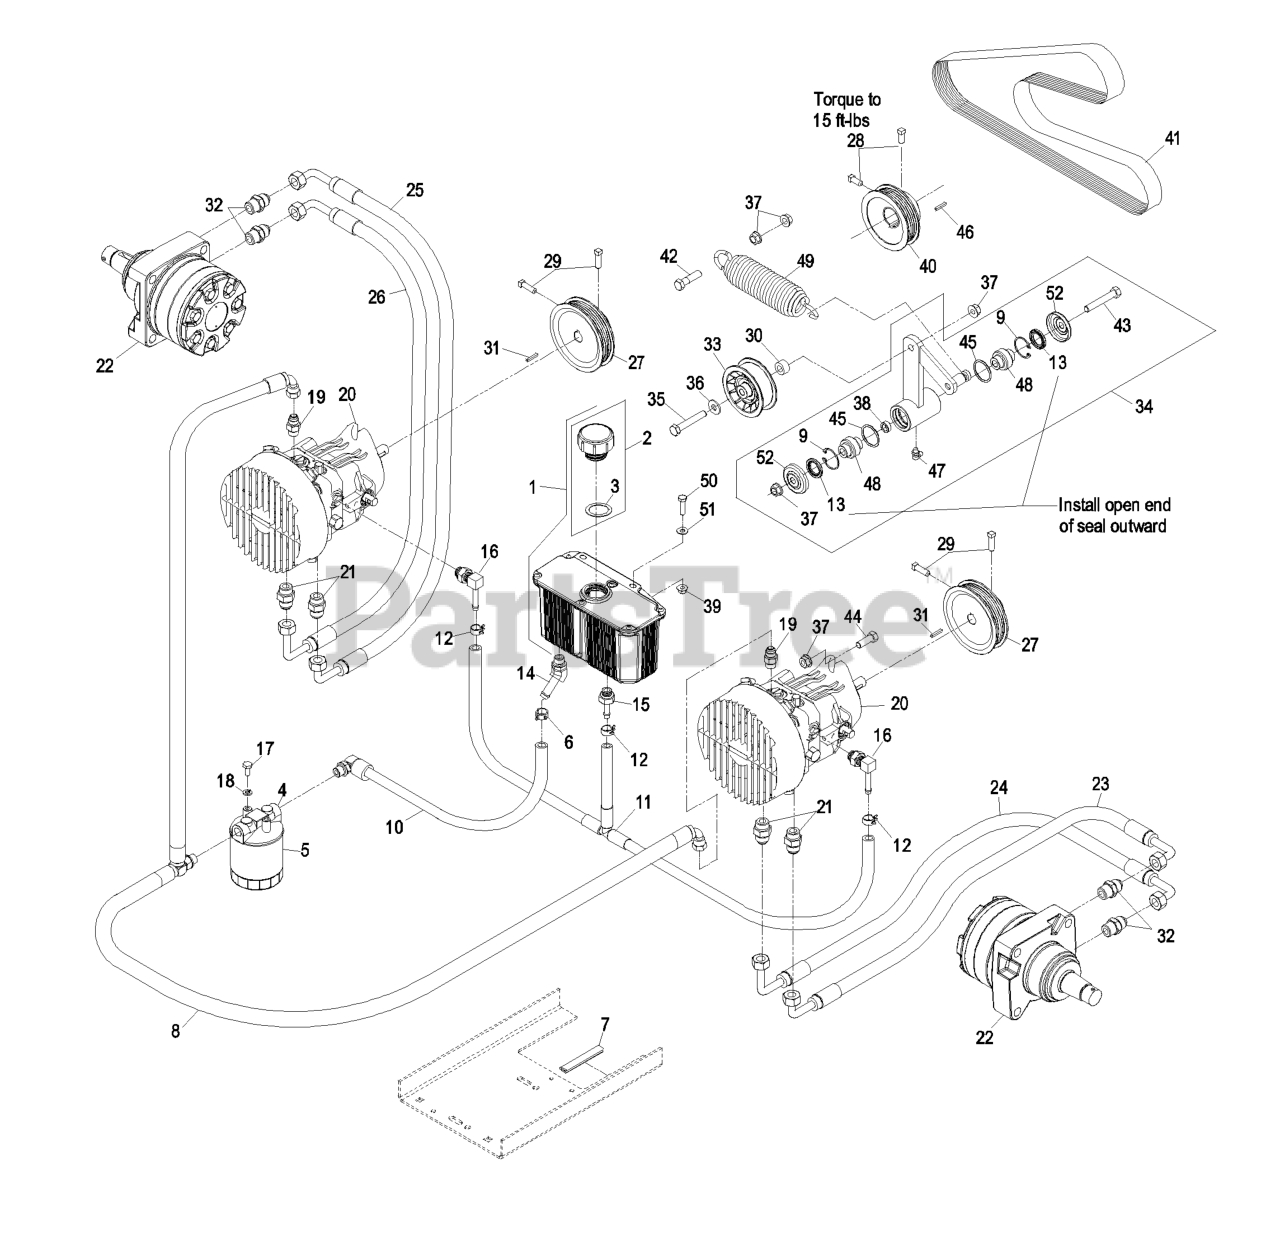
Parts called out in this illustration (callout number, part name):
1	HYD RESERVOIR ASM
2	KIT,HYD RES CAP W/GASKET
3	GASKET-CAP
4	HEAD-FILTER
5	FILTER-25 MICRON, BI-DIRE
6	CLAMP-HOSE
7	STRIP-SEAL
8	HYD HOSE ASM
9	RING-SNAP
10	HYD HOSE ASM
11	HYD HOSE ASM
12	CLAMP-HOSE
13	SEAL-LIP, SINGLE
14	FITTING-BARBED, 45 DEG
15	ADAPTER-STRAIGHT
16	ELBOW-90 DEG
17	SCREW-HH
18	WASHER-LOCK
19	FITTING-STRAIGHT
21	FITTING-STRAIGHT
22	MOTOR-WHEEL
23	HYD HOSE ASM
24	HYD HOSE ASM
25	HYD HOSE ASM
26	HYD HOSE ASM
28	SCREW-SET
29	SCREW-SET
31	KEY-SQUARE
32	FITTING-STRAIGHT
33	PULLEY-FLAT IDLER
34	KIT,PUMP IDLER LZ
35	SCREW-HH
36	WASHER-FLAT
37	NUT-HHF, WHIZ
41	BELT
42	SCREW-HH
43	SCREW-HH
44	SCREW-HH
46	KEY-SQUARE
47	FITTING-GREASE, 90 DEG
48	BEARING-SPHERICAL
50	SCREW-HH
51	WASHER-FLAT
52	GUARD-TOP
